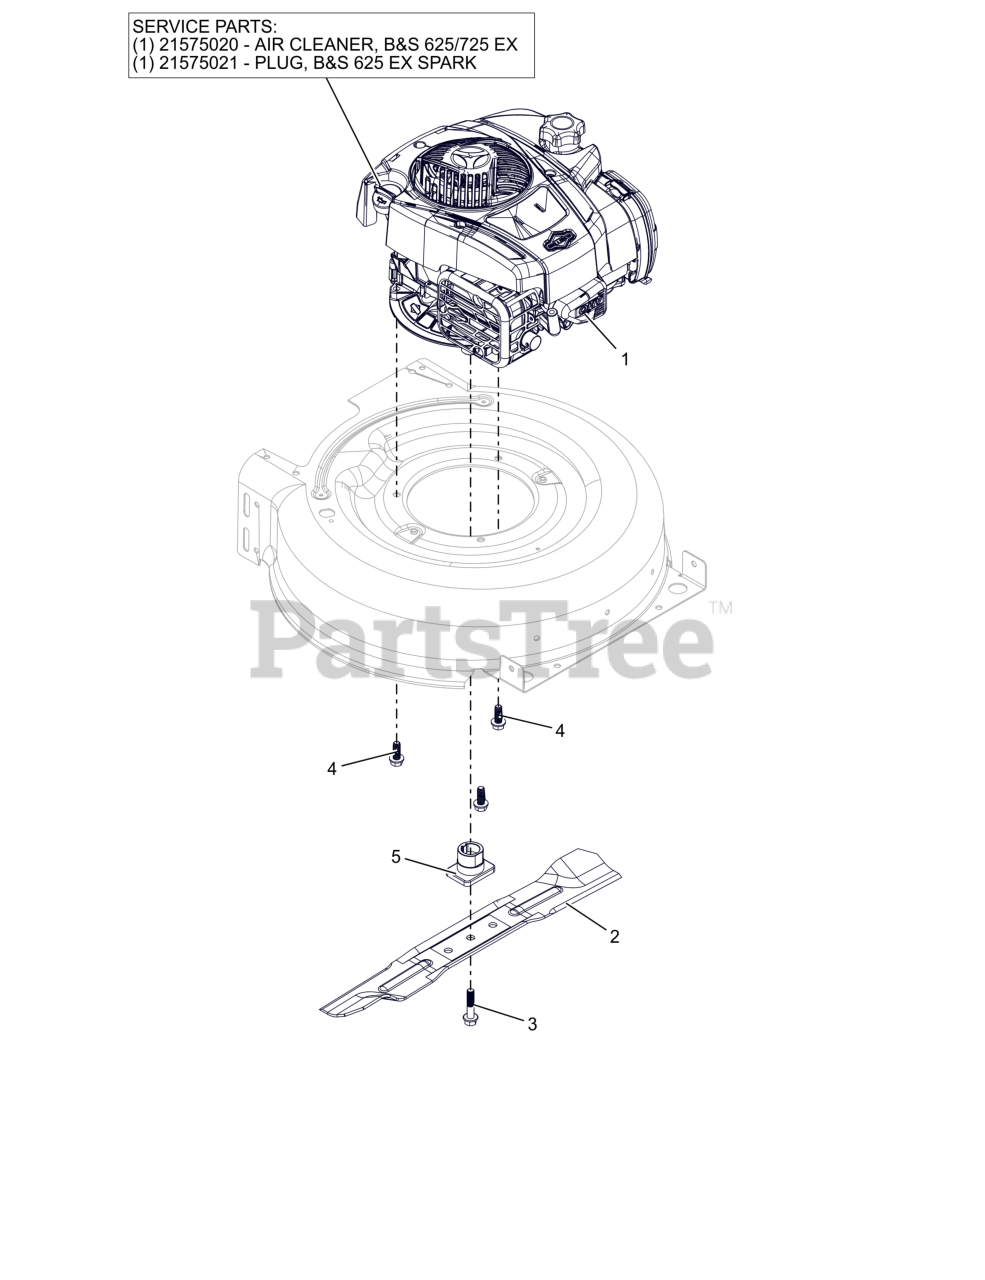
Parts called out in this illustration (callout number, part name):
1	ENGINE, BRIGGS 625 EX
1	AIR CLEANER- B&S 625/725 EX
1	PLUG- B&S 625 EX SPARK
2	BLADE, MOWER 21" HIGH LIFT
3	SCR, HEX FLANGE 3/8-24X1.75
4	SCR-TAP, 3/8-16X1.00 HWH
5	SPCR, BLADE - PUSH
